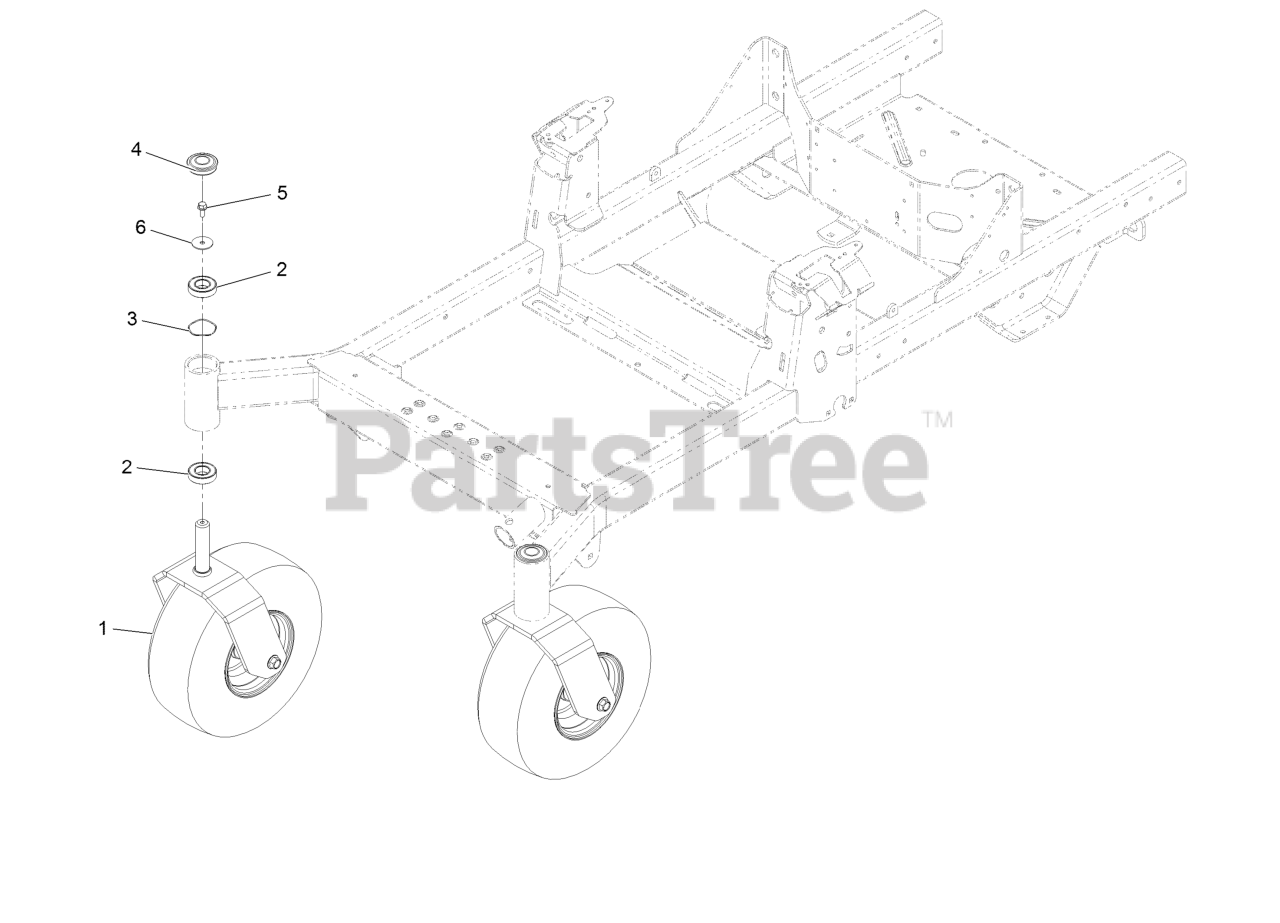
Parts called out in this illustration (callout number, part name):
1	ASM-Front Caster W/Fork
2	Bearing-Ball
4	Cap-Grease
5	Screw-HH Flg 5/16-18 X 3/4
6	Washer-Flat
